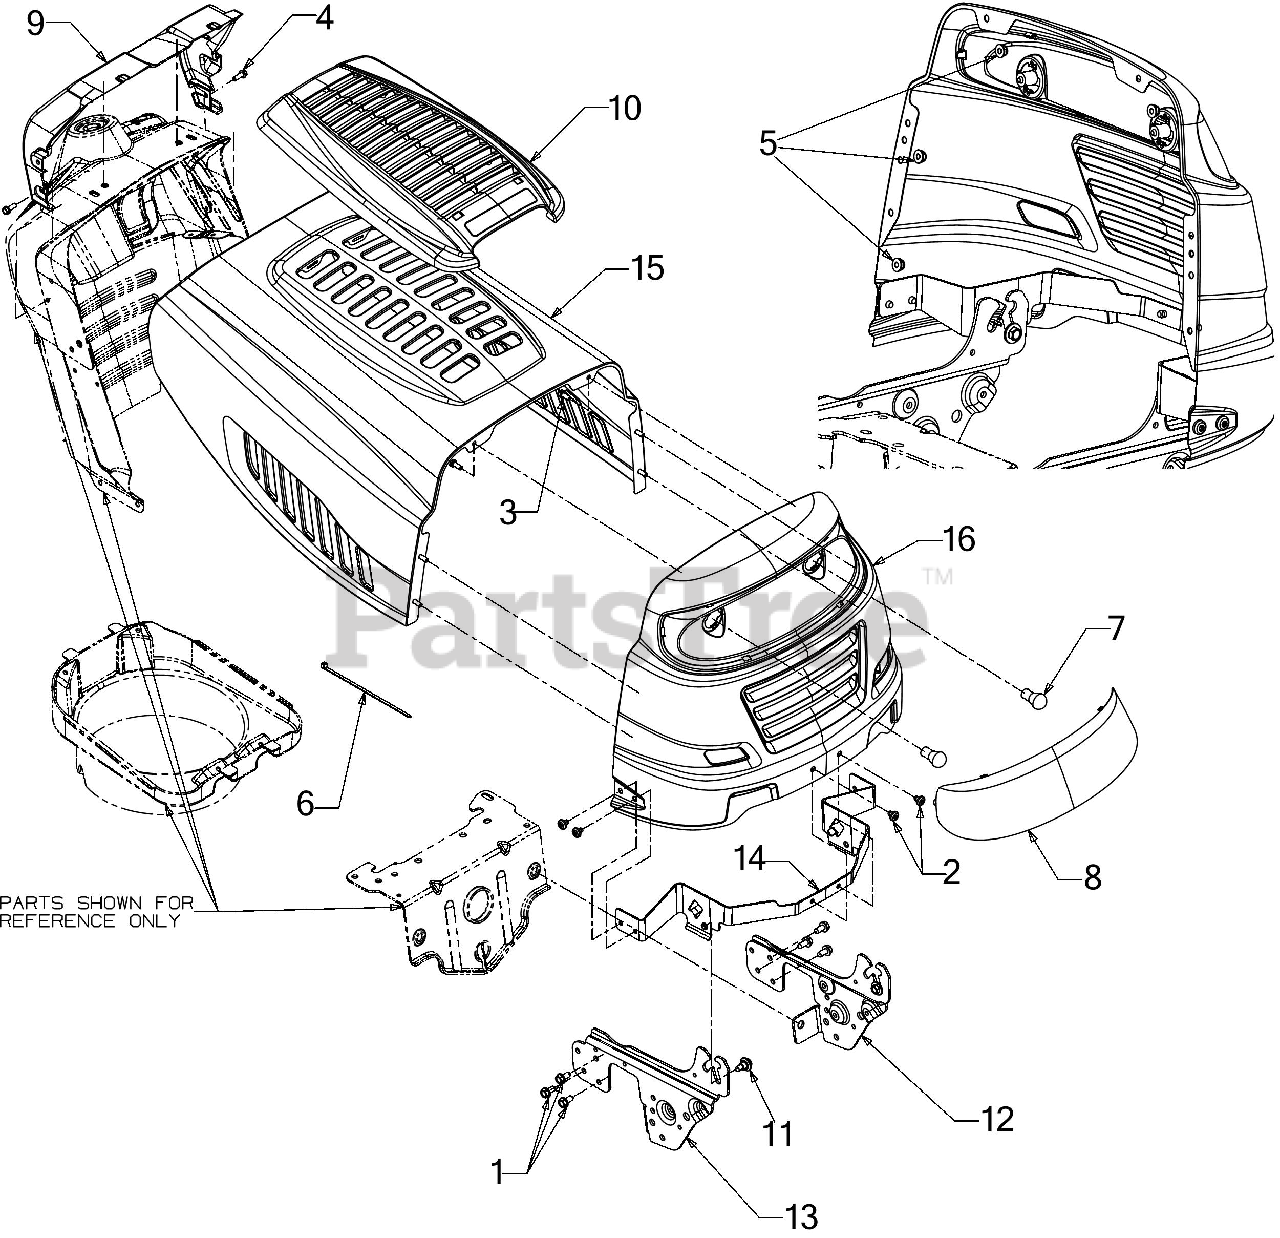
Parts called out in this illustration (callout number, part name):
1	SCREW 5/16-18 x .750
2	SCREW 5/16-18 x .375
3	SCREW 1/4-20 x .620 GR5
4	SCREW 1/4-15 x .750
5	FLANGE LOCK NUT
6	7" CABLE TIE
7	MINIATUURE BULB 12V
8	GRILL LENS
9	DASH COLLAR
10	HOOD COVER
11	SHOULDER SCREW .43X.29X5/16-18 TT
12	SUPPORT BRACKET (LH)
13	SUPPORT BRACKET (RH)
14	HOOD PIVOT BRACKET
15	HOOD-5-STYLE
16	GRILLE-1 STYLE
